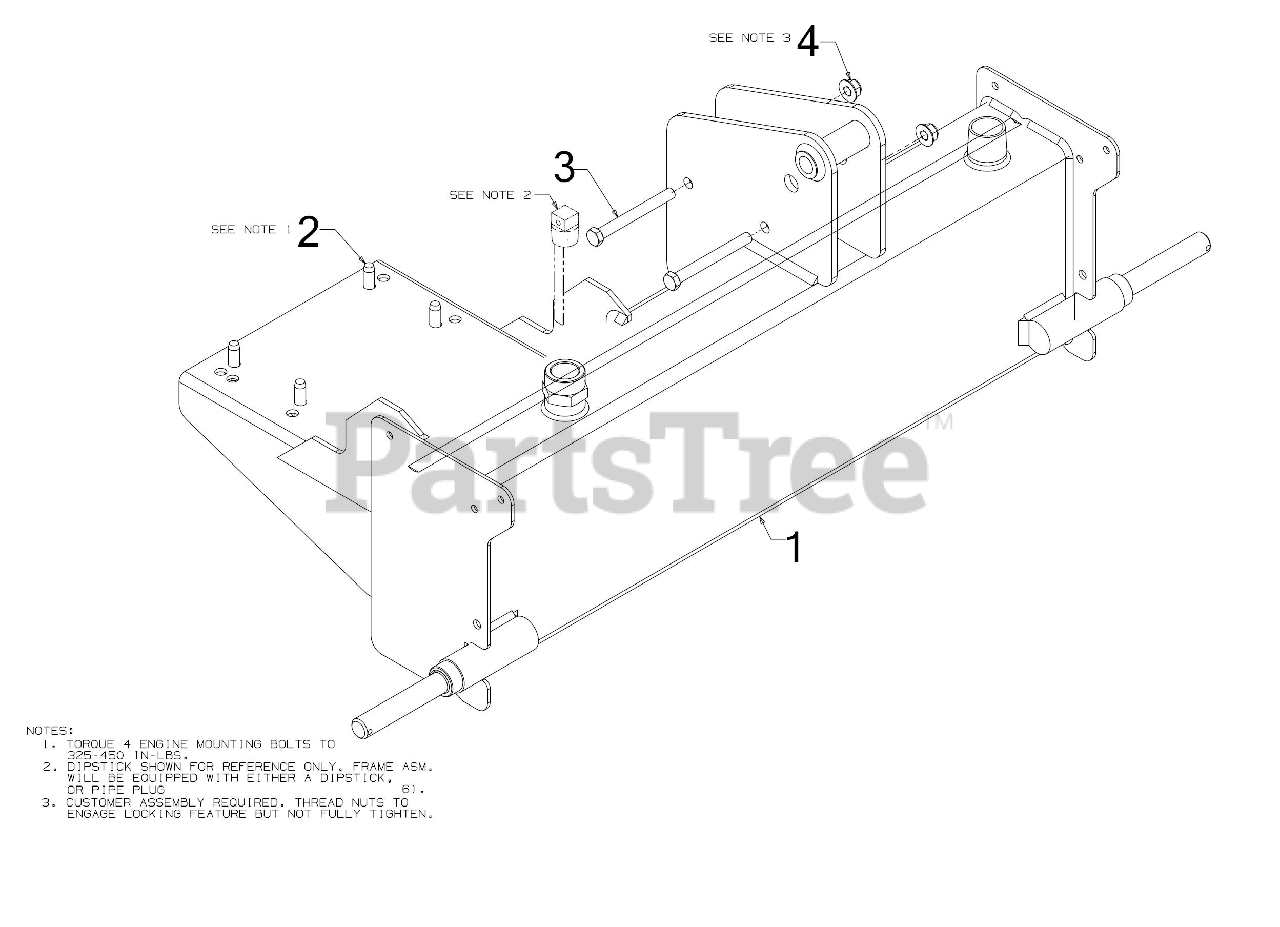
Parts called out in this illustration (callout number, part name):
1	TANK ASSEMBLY
2	SCREW 3/8-16 x 1
3	SCREW 3/8-16 x 3.50 GR5
